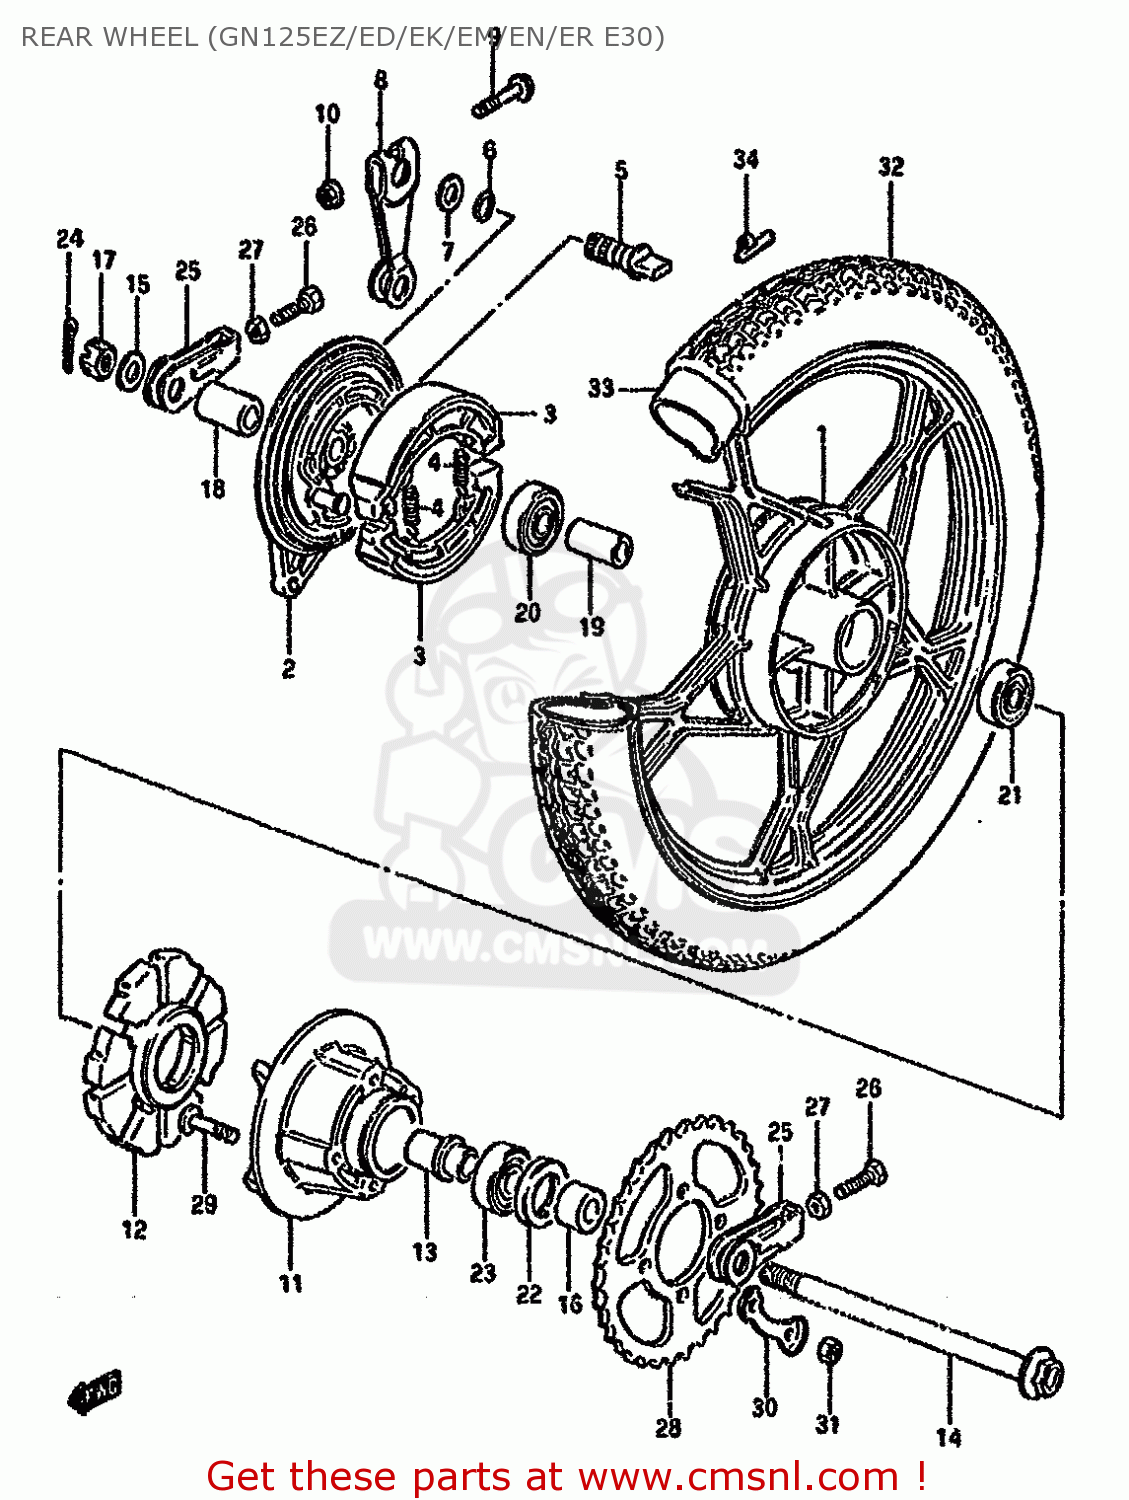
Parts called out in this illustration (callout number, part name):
1	WHEEL,RR(2.15X10)
2	PANEL,RR BRAKE ANCHOR
3	SHOE,BRAKE
4	SPRING(L:34)
5	CAM,FRONT BRAKE
6	O-RING (D:2.4 ID:13.8)
7	WASHER (14.5X22X1.6)
8	LEVER,RR BRAKE CAM
9	BOLT
10	NUT
11	DRUM,RR SPROCKET MOUNTING
12	ABSORBER,RR HUB SHOCK
13	RETAINER,RR SPROCKET DRUM
14	AXLE,RR
15	WASHER
16	SPACER(15X28X19)
17	NUT
18	SPACER(15.2X26X33)
19	SPACER(15.3X21.7X63)
20	BEARING
21	BEARING
22	SEAL,OIL(28X47X7)
23	BEARING(20X47X14)
24	COTTER PIN
25	ADJUSTER,CHAIN
26	BOLT
27	NUT
28	SPROCKET,REAR
29	BOLT
30	WASHER
31	NUT
32	TIRE
33	TUBE
34	BALANCER,WHEEL
